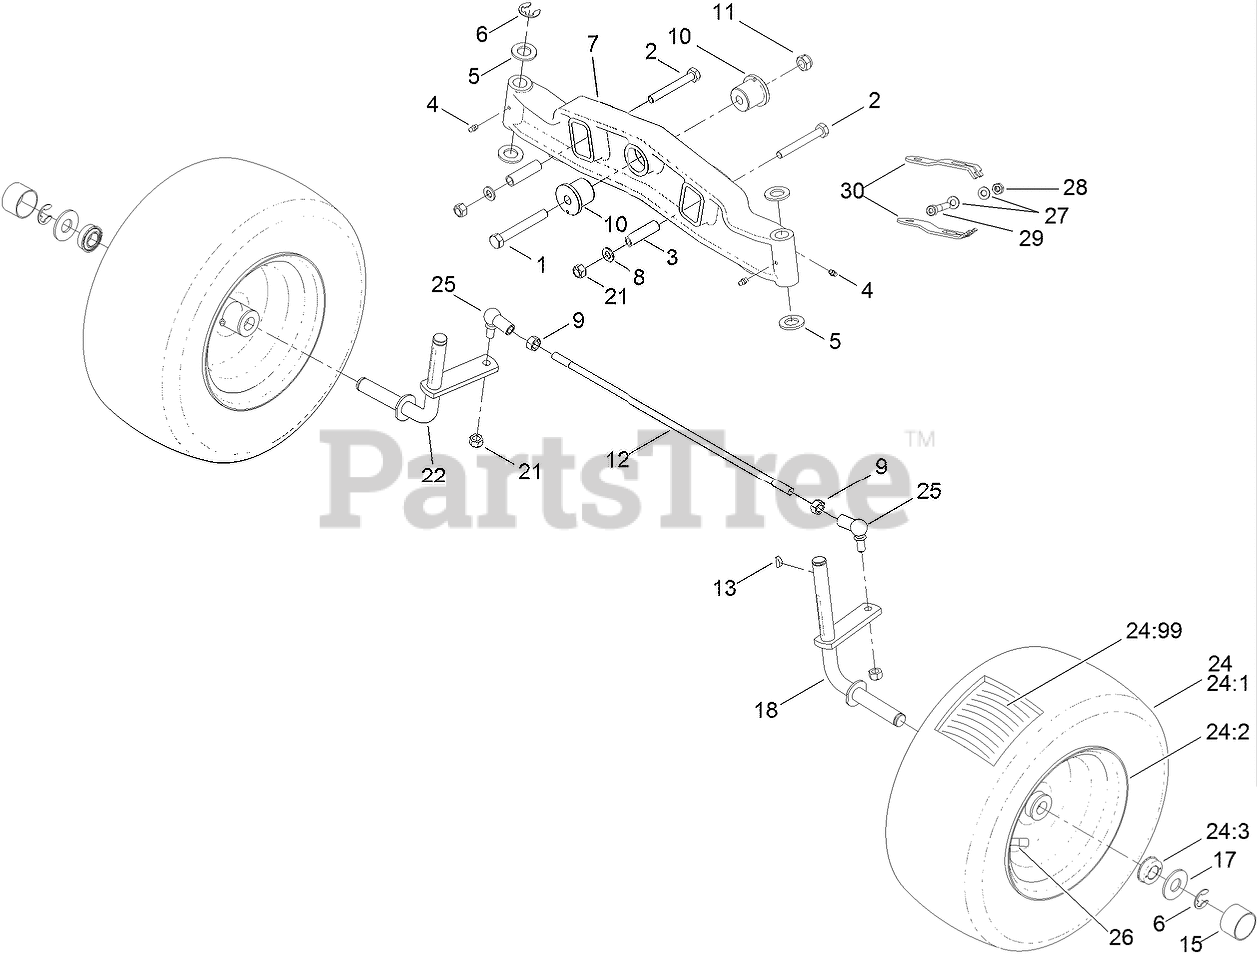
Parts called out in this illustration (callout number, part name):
1	SCREW-HH
2	SCREW-HH
3	SPACER
4	FITTING-GREASE
5	WASHER-FLAT
6	CLIP-SPRING
7	AXLE-FRONT
8	WASHER-FLAT
9	NUT
10	BUSHING-AXLE, FRONT
11	NUT-LOCKING, SELF
12	ROD-TIE, FRONT AXLE
13	KEY-WOODRUFF
15	CAP-HUB
17	WASHER
18	SPINDLE-FRONT, LH
21	NUT-LOCK, NI
22	SPINDLE-FRONT, RIGHT
24	WHEEL ASM
24:2	RIM-FRONT
24:3	BEARING-WHEEL
24:99	TUBE-INNER
25	JOINT-BALL, ANGLE
26	Valve-Tire
27	WASHER-PLAIN
28	NUT-LOCK, NI
30	LEVER-SPINDLE, STEERING
